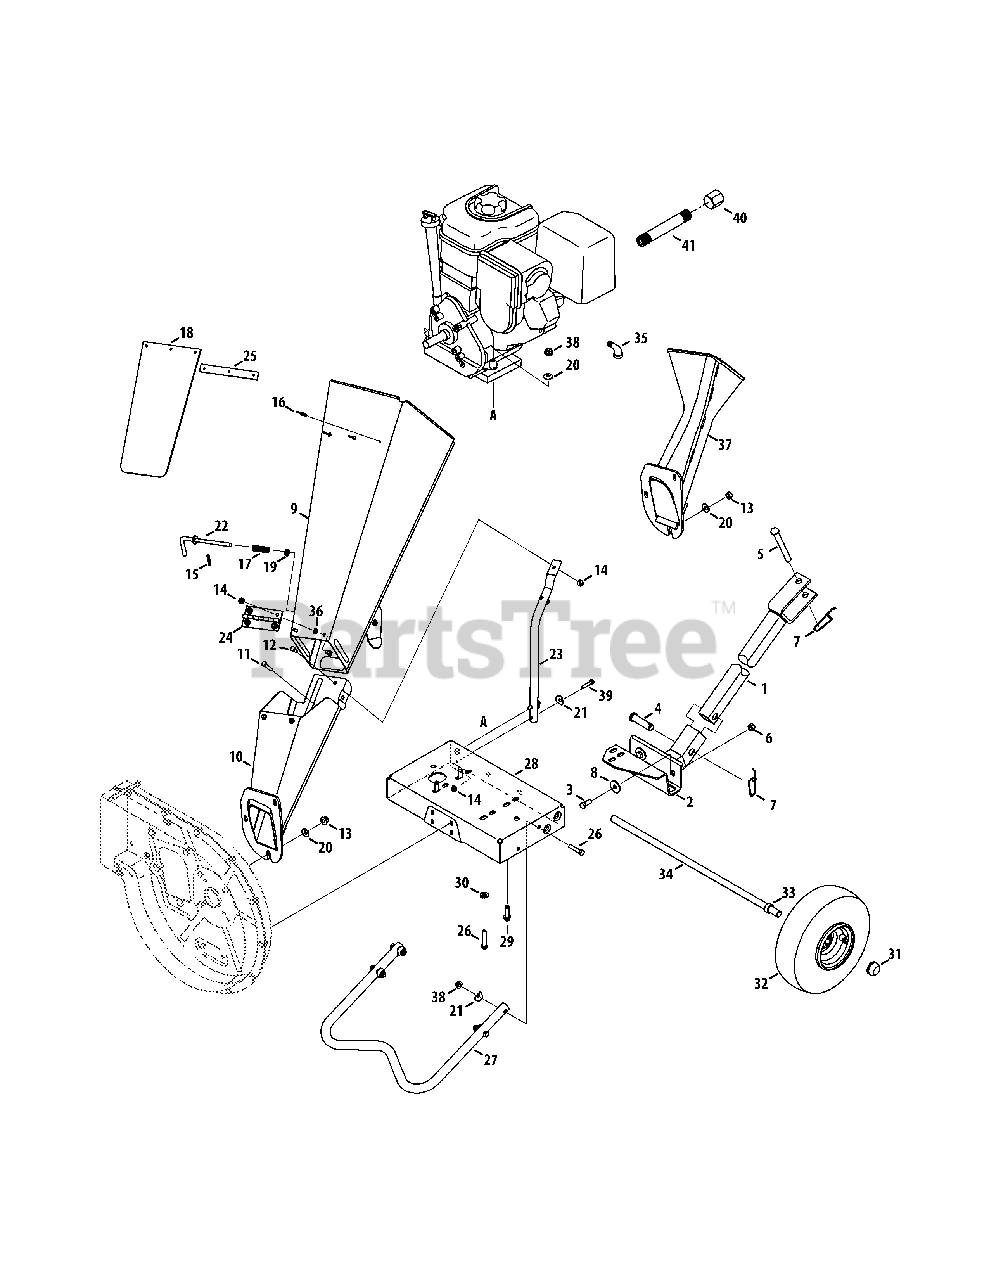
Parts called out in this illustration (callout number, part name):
1	Tongue Hitch Mount
2	Base Hitch Mount
3	Hex Cap Screw, 3/8-16 x.88
4	Clevis Pin,.625 x 2.4
5	Clevis Pin,.50 x 4.62
6	Flange Lock Nut, 3/8-16
7	Spring Pin
8	Flat Washer,.411 x 1.25 x 1.0
9	Upper Chipper Chute Assembly
10	Lower Chipper Chute Assembly
11	Hex Cap Screw, 1/4-20 x 1.25
12	Screw, 1/4-20 x .50
13	Hex Nut, 5/16-18
14	Flange Lock Nut 1/4-20
15	Cotter Pin
16	Pop Rivet
17	Compression Spring,.531 x 1.75
18	Chute Flap
19	Flat Washer
20	Bell Washer.340 ID x.872 OD
21	Washer,.320 ID x.93 OD
22	Lock Rod
23	Chipper Chute Support
24	Chipper Chute Hinge
25	Chute Flap Strip
26	Hex Cap Screw, 5/16-18 x 1.50
28	Frame Assembly
29	Hex Sems Screw, 3/8-16 x 1.25
30	Special Lock Washer, 5/16
31	Push Cap, 5/8
32	Wheel, 10 x 4 x 4
33	Spacer, .64 x .88 x .38
34	Axle, 22.47"
35	Elbow Fitting
36	Push Nut,.25ID x.50OD
37	Chipper Chute
38	Flange Lock Nut, 5/16-18
39	Hex Cap Screw, 1/4-20 x 1.250
40	End Cap, 1/4 NPT
41	Pipe, 1/4 NPT x 3.5 LG
